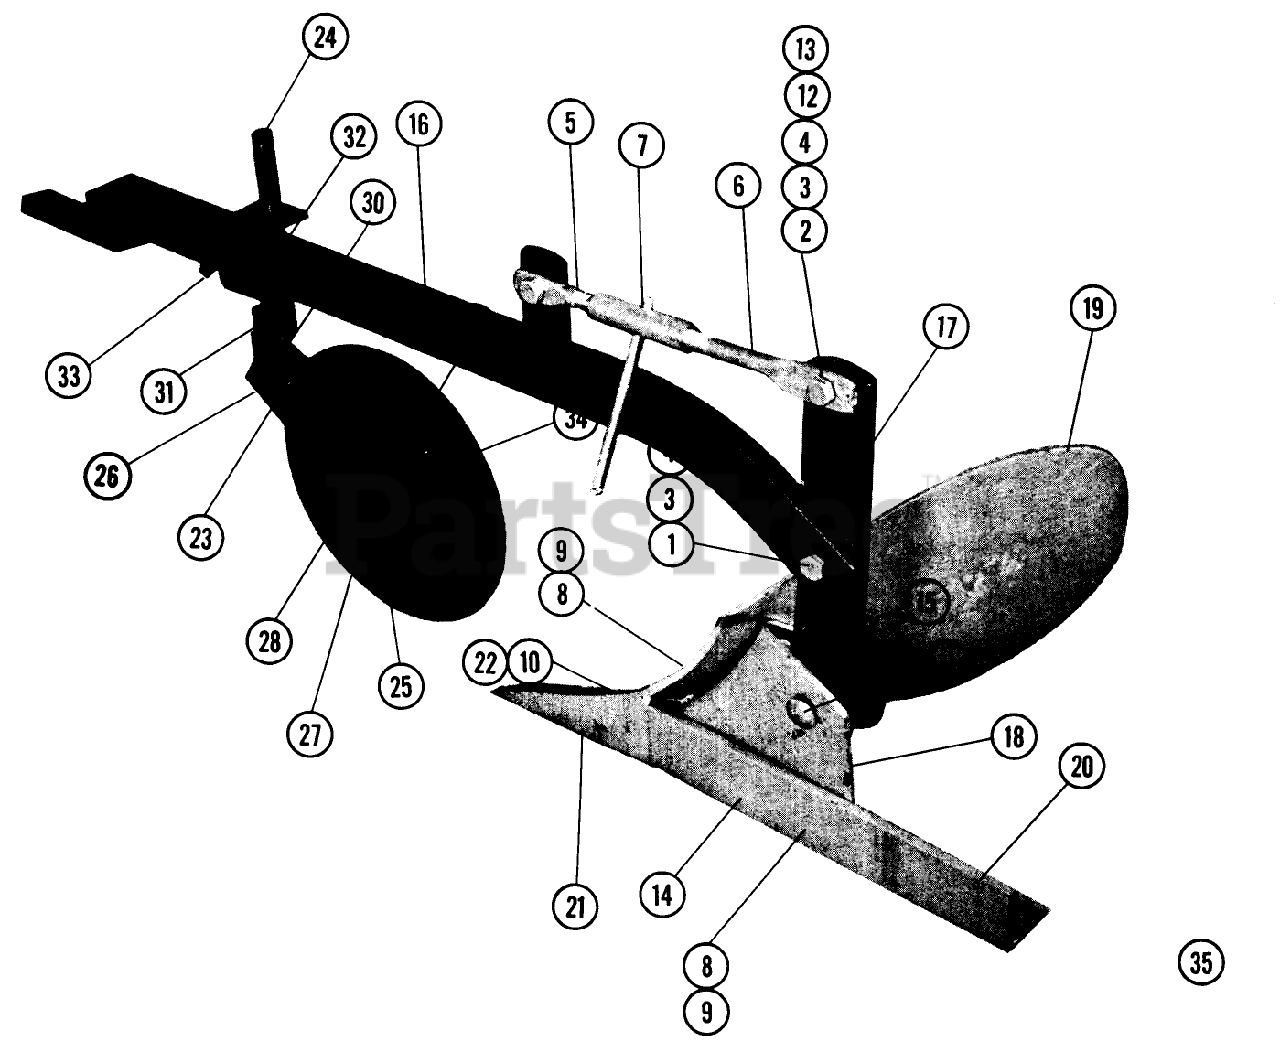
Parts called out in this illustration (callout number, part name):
1	Bolt-Hex 1/2-13 x 2
2	Bolt Hex 1/2-13 x 1 1/2
3	Lockwasher
4	Nut, 1/2-13
7	Coupling-Adjusting
8	Bolt-Plow 3/8-16 x 1
9	Nut-Sq. 3/8-16
10	Nut-Sq. 7/16-14
11	Nut-Sq. 1/2-13
12	5353 GILSON LGT WEI
13	Washer 9/16 SAE
14	Bolt-Plow 1/2-13 x 1-1/4
15	Bolt-Carriage 1/2-13 1 1/4
16	Ass-y. Beam
17	Standard Base
18	Frog Br.
19	Moldboard
20	Landslide Br.
21	Point 8" Br.
22	Bolt-Plow 7/16-14 x 1
23	Frame Assembly
24	Coulter, Standard Ass-y.
25	Axle
26	Roll Pin
27	Hub Assembly
28	Blade, Coulter
29	Rivet, 3/16 x 3/8
31	Clamp
33	Set Screw, 3/8-16 x 1-1/4
